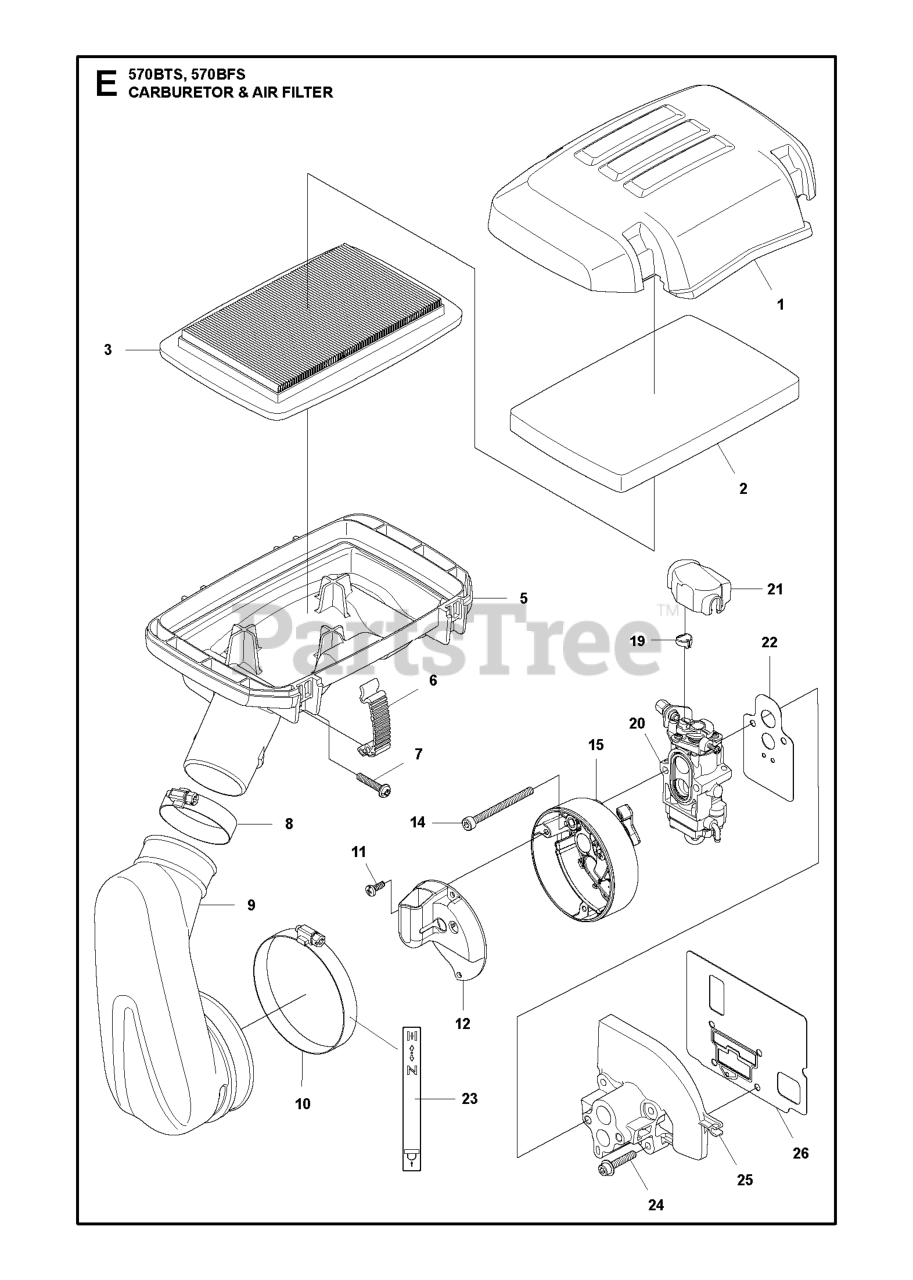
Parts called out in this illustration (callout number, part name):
1	COVER AIR FILTER
2	ELEMENT
3	ELEMENT
5	HOLDER AIR FILTER
6	BUCKLE ORANGE
8	CLAMP(F64)
9	HOSE AIR FILTER
10	CLAMP(F96)
